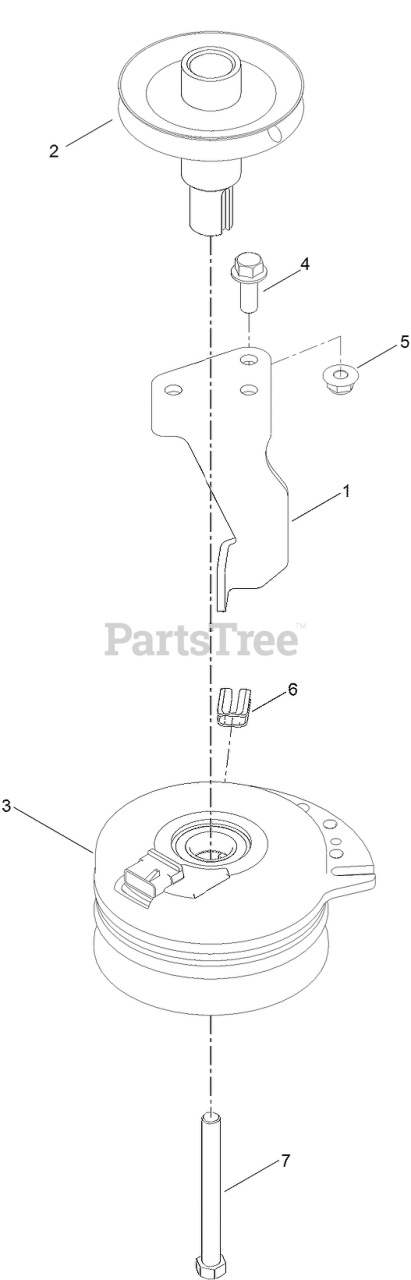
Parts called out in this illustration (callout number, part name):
1	STOP - CLUTCH (NARROW)
2	PULLEY-ENGINE
3	CLUTCH-ELECTRIC
4	SCREW-HHF
5	NUT-HF, NI
6	ISOLATOR-CLUTCH
7	SCREW-HH
